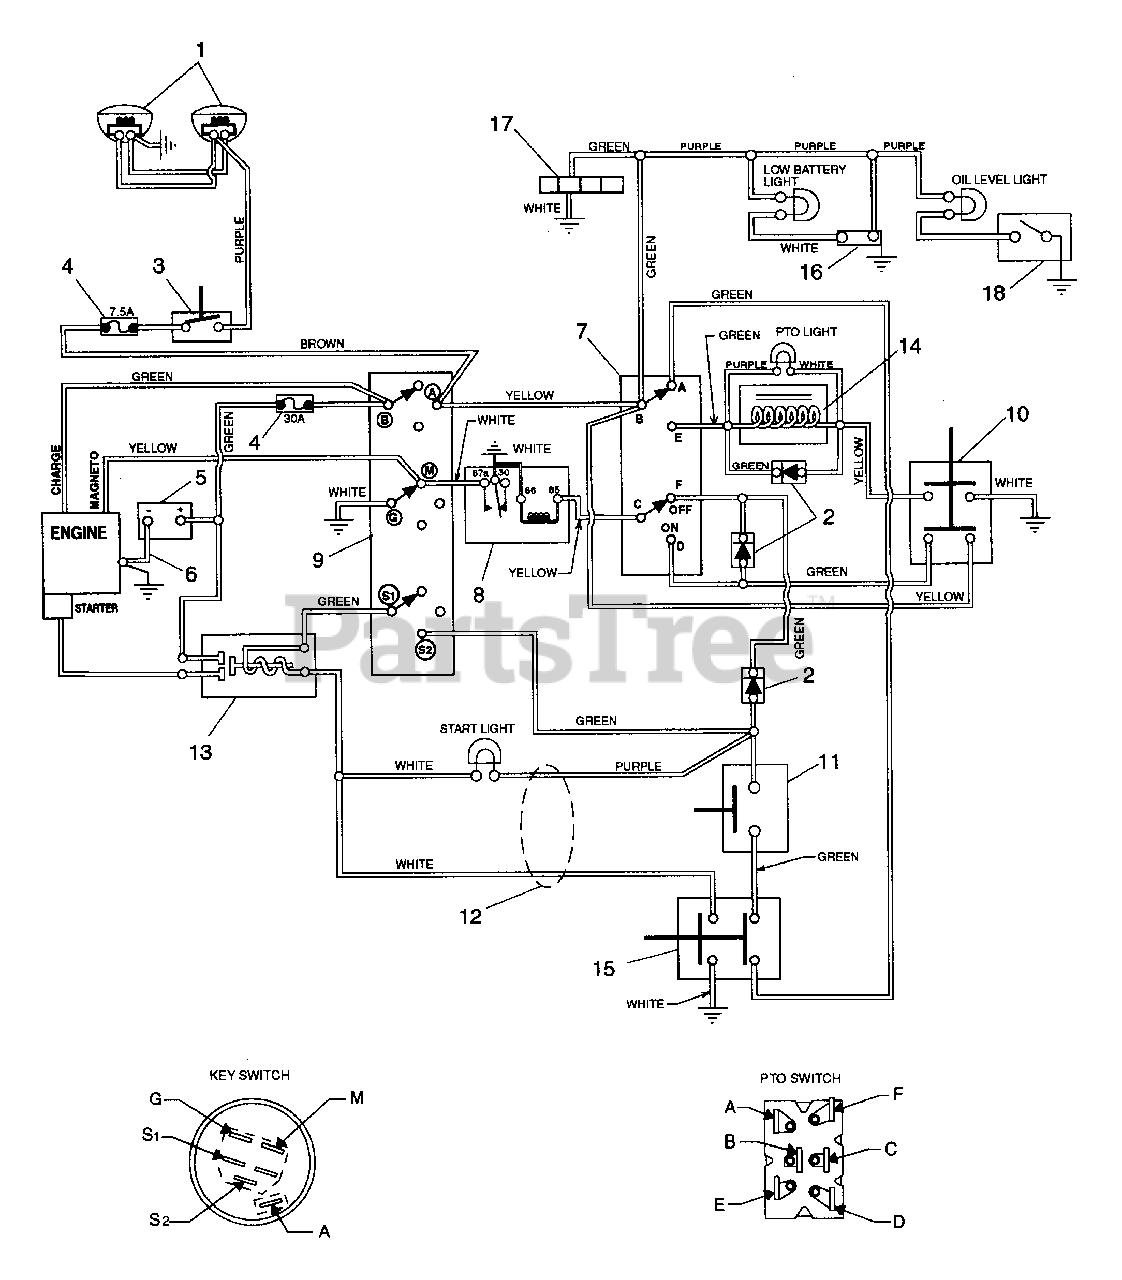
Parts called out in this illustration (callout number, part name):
1	HEADLIGHT- L.H.
1	HEADLIGHT- R.H.
2	DIODE & HOUSING
3	LIGHT SWITCH
4	7.5 AMP FUSE
4	30 AMP FUSE
5	BATTERY
6	GROUND CABLE .31X22.00X.31
7	SWITCH ASSEMBLY- PTO
8	RELAY
9	KEY SWITCH
10	SWITCH- DOUBLE POLE N.O./N.O.
11	SWITCH-NEUTRAL START N.O.
12	WIRE HARNESS- YT15H
13	SOLENOID
14	ELECTRIC CLUTCH/BRAKE(1.8AMP)
15	SWITCH- DOUBLE POLE N.C./N.C.
16	VOLTAGE SENSOR
17	HOUR METER W/ LEADS
18	OIL SENSOR- FASCO #0454-0513
